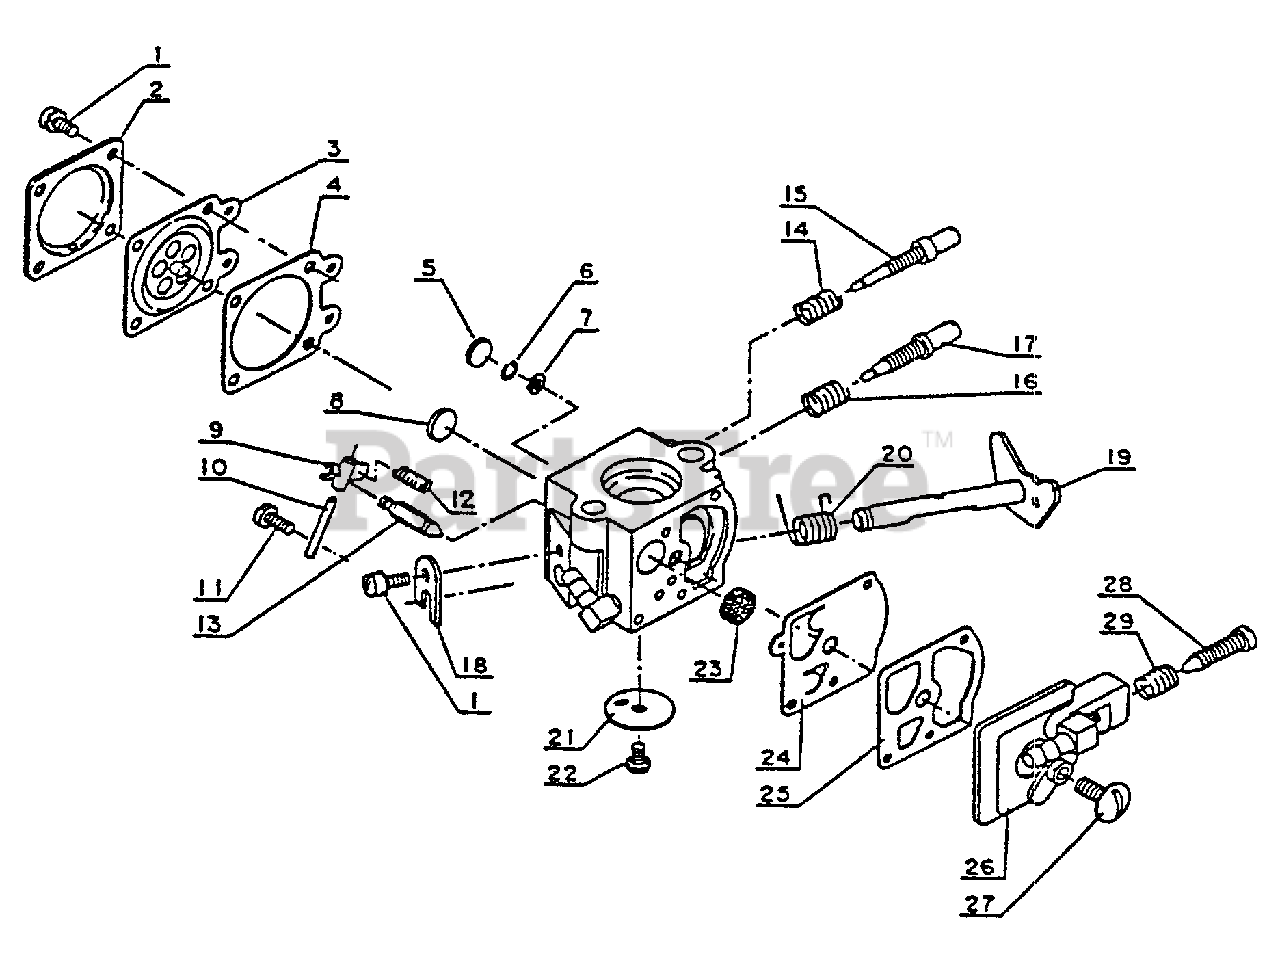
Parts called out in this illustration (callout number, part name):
1	SCREW
2	COVER, METERING
3	DIAPHRAGM, METERING
4	GASKET, METERING
5	PLUG, WELCH
6	RING, RETAINING
7	STRAINER
8	PLUG, WELCH
9	LEVER, METERING
10	PIN, METERING LEVER
11	SCREW, METERING LEVER PIN
12	SPRING, METERING LEVER
13	VALVE, INLET NEEDLE
14	SPRING
15	NEEDLE - HIGH SPEED
16	SPRING
17	NEEDLE - LOW SPEED
18	CLIP, THROTTLE SHAFT
19	SHAFT, THROTTLE
20	SPRING, THROTTLE RETURN
21	VALVE, THROTTLE
23	STRAINER
24	DIAPHRAGM, PURGE
25	GASKET, PURGE
26	COVER, PUMP
27	SCREW, PUMP COVER
28	SCREW, IDLE ADJUST
29	SPRING, IDLE ADJUST
